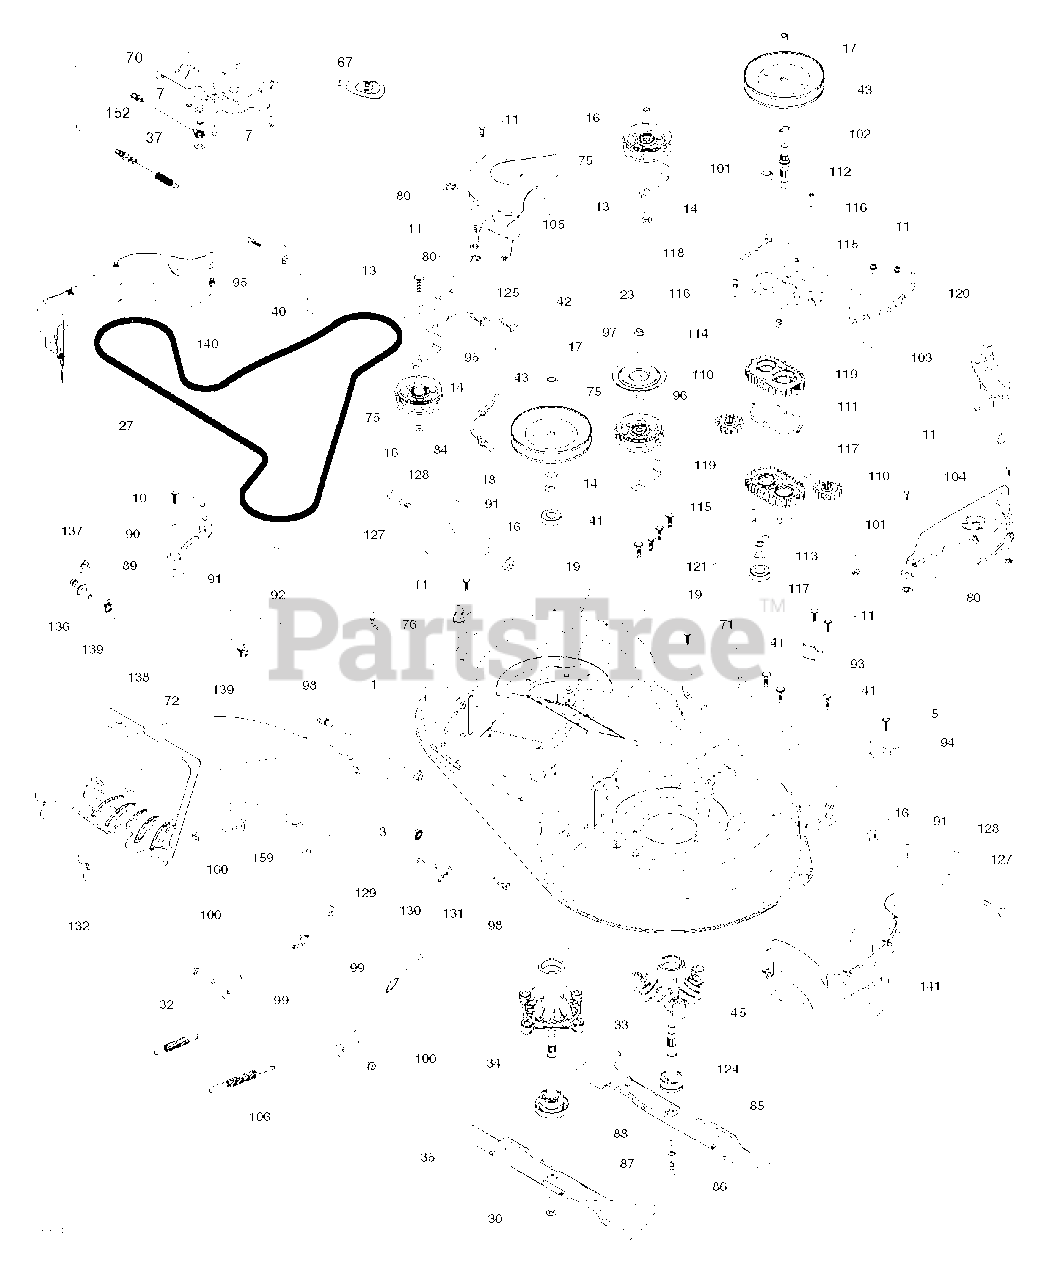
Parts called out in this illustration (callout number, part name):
1	DECK.WELDMENT.97.TEX.498
3	NUT LOCK HEX FLANGE 5/16-18
5	BOLT.5/16HEX.WHS.HD
7	SCREW.#10 X 0.750.BOS
10	SCREW 3/8-16X1
11	SCREW.1/4-20X5/8
13	BOLT.3/8-16X1.50
14	KEEPER, BELT IDLER
16	NUT LOCK FLG 3/8-16 UNC
17	NUT.FLANGE.LOCK.TOP
18	WASHER.SPACER.MANDREL
23	SCREW LT
27	BELT V-BELT DRIVE
30	SCREW.SEMS.7/16-20X1.HEX.HEAD
32	SPRING RETURN
33	HOUSING.MANDREL.4PT.
34	SHAFT.ASM.MDRL.N/GREASE.38
35	BLADE.3N1.LH.CRD.97
37	WASHER
40	KEEPER BELT ENGINE LH
41	BOLT.HEX.WASHR.HED.313-18X1.19
42	SCREW
43	PULLEY.MANDREL.5.438.PD
45	HOUSING.MANDREL.44/46" VENT
67	HANDLE.CLUTCH.CABLE.LT
70	CLUTCH.ASM.MANUAL.LT.PRED
71	SCREW 3/8-16X1/2
72	CHUTE REAR CRD UPPER CHUTE TEX
75	FLAT IDLER PULLEY
76	1/2" BARB.DECK.WASHOUT.PORT
80	PALNUT 1/4
84	KEEPER.BELT.MANDREL.PULLEY
85	BLADE.3N1.RH.CRD.97
86	BOLT.3/8-24X1.25GR8. LHTHRD
87	LOCKWASHER
88	WASHER.BLADE
89	ARM.BRAKE.97.LH
90	SPACER.RETAINER
91	WASHER
92	ROD ROD BRAKE
93	ARM.BRAKE.97.RH
94	BRKT.CLUTCH.CABLE
95	SCREW, 3/8-16X3/4
96	SPACER
97	PROTECTOR
98	STUD.FASTNER.W/ANTI-ROTATE
99	ARM.SUSPENSION.MOWER.R
100	BOLT.SHOULDER
101	NUT.CROWNLOCK.9/16 -18.UNC
102	SPACER BEARING
103	GUARD GUARD FRONT VENT
104	97.CRD.RH.MANDREL.COVER
105	MANDREL MANDREL COVER LH
106	SPRING.BRAKE.RETURN.38"
110	CRD.SPUR.GEAR
111	GASKET GASKET GEARCASE
112	SHAFT SHAFT. CRD GEARCASE ADAP
113	PLUG PLUG OIL
114	VENT.BREATHER.1/8 NPT
115	SCREW
116	BOLT.CARIGE.SS.1/4-20X1.75GR5
117	NUT T
118	ARM ARM CLUTCHING
119	GEARCASE GEARCASE SUBASM
120	BRACKET KEEPER BELT RH
121	WASHER WASHER
124	MANDREL SHAFT NON/GREASE
125	BRACKET BRACKET IDLER CHASSES
127	BOLT.SHOULDER.3/8-16X3-5/8.
128	WHEEL. GUAGE RALLY
129	ROD.ANTI.SWAY.48/54"K4
130	WASHER
131	PIN.COTTER.5/16.BOW TI
132	KNOB.HANDLE.3/8.TRI-POINT.BLAC
136	PLUG WASHOUT PORT HOOKUP
138	HOSE.3/8ID.BULK.12"
139	HOSE.3/8.CLAMP (2 2)
140	GUARD
141	GUARD SUBASM.TEX CRD 97CM RH F
152	CABLE CABLE CLUTCH MANUAL W/S
